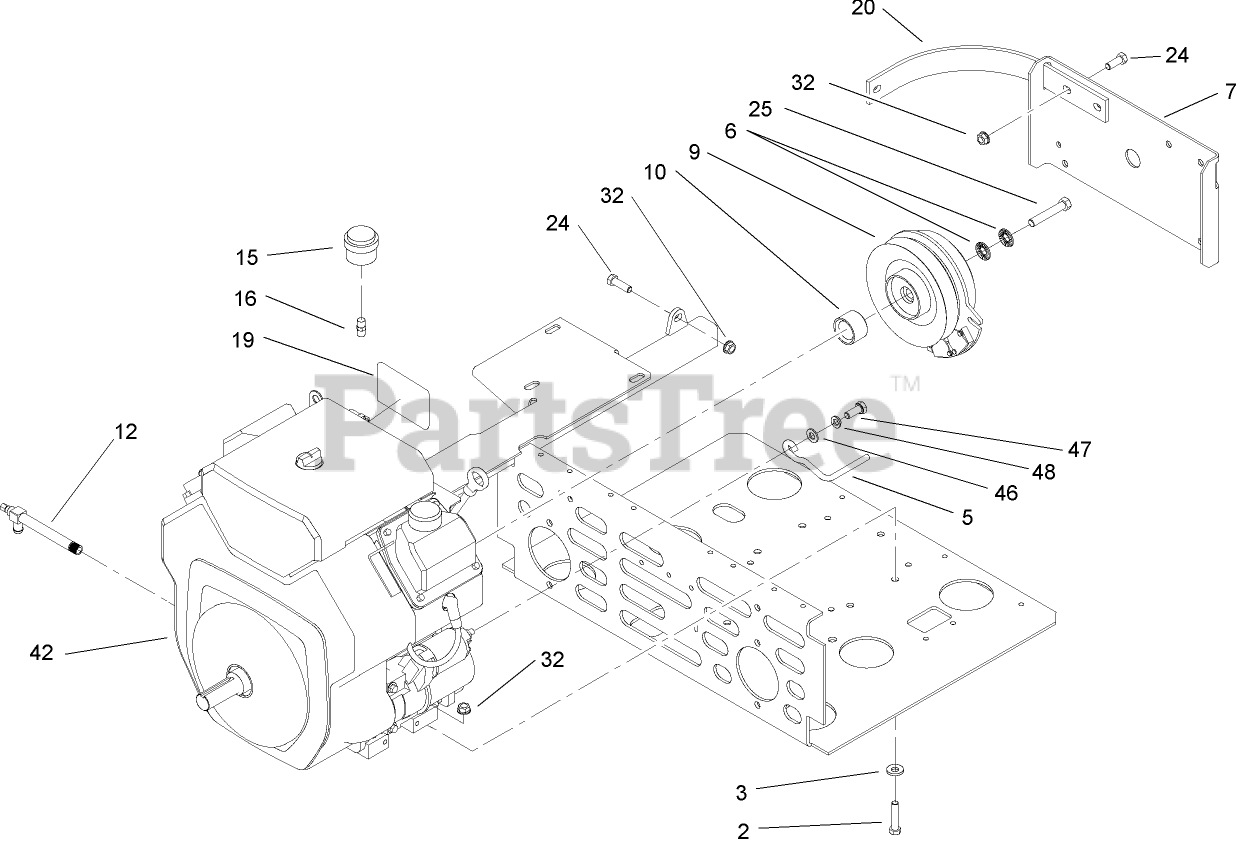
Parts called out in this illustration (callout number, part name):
2	SCREW-HH
3	WASHER-BELLEVILLE
5	ROD-BELT
6	WASHER-SPRING
7	GUARD-CLUTCH
10	SPACER-CLUTCH
12	VALVE-OIL DRAIN, LONG
15	INDICATOR-FILTER, AIR
16	ADAPTER-INDICATOR
20	STRAP-GUARD
24	SCREW-HH
25	SCREW-HH
32	NUT-HHF, WHIZ
42	HUB and BEARING ASM
46	WASHER-FLAT
47	SCREW-HH
48	WASHER-BELLEVILLE
